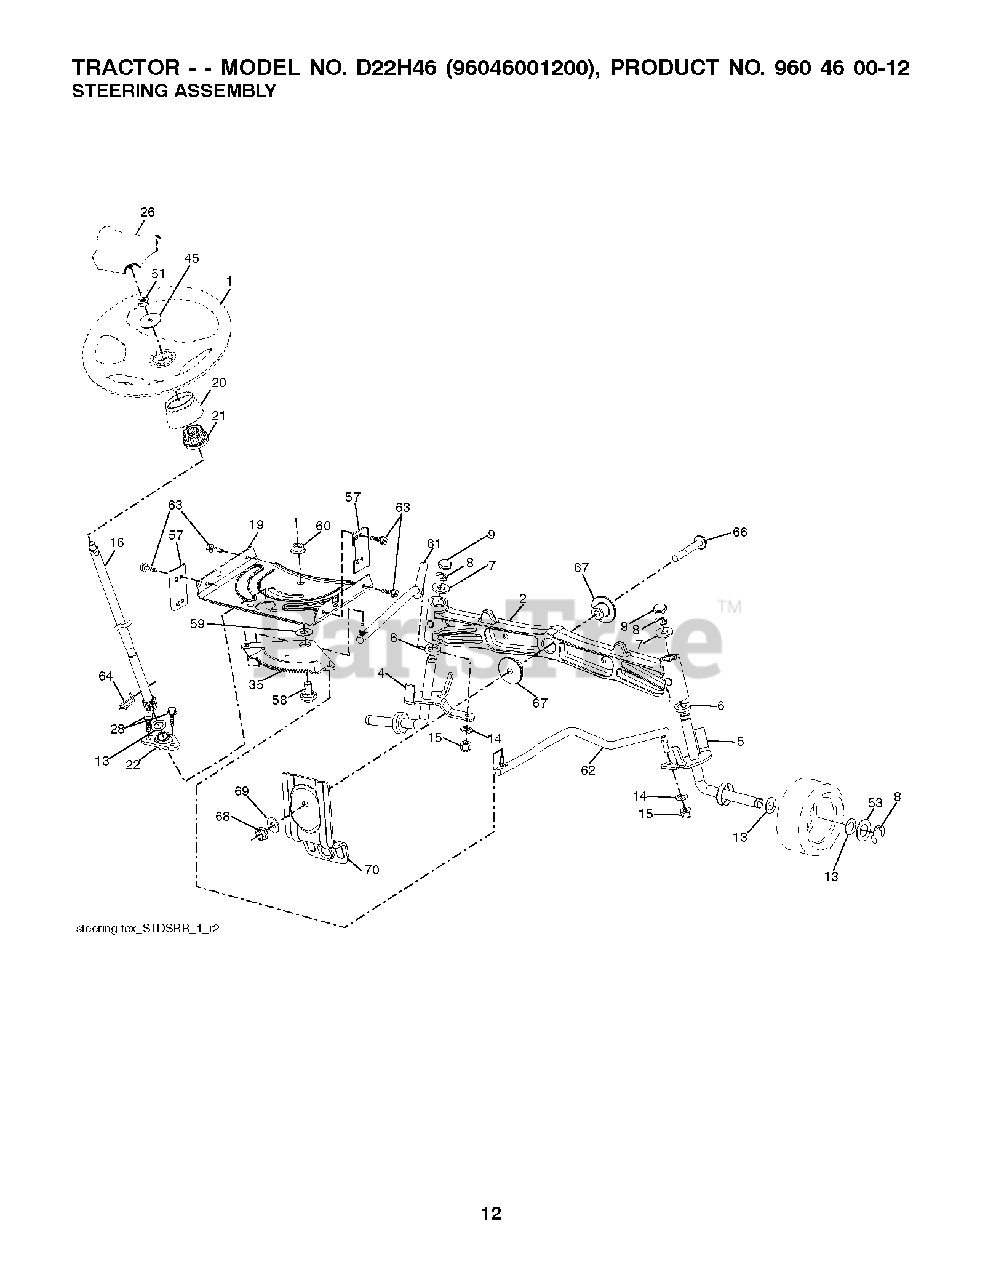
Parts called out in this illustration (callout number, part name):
1	WHEEL.STEERING.STDSRR.BLK/OV
2	AXLE.CAST.IRON
4	SPINDLE.WELDED.LH.15"TEX
5	SPINDLE.WELDED.RH.15"T
8	RING CLIP
9	CAP.SPINDLE.BLACK
14	WASHER, LOCK 3/8
15	NUT CROWNLOCK 3/8-24
16	SHAFT, STEERING
19	PLATE.STEER.DDL.NLT/NG
20	BOOT.STEERING.
21	ADAPTER, WHEEL STNG..
22	STEERING.SUPT.LOWER.
26	INSERT, WHEEL STEERING
28	SCREW, 3/8-16X3/4
35	GEAR.SECTOR.PLATE.DDL.
45	WASHER.11/32
51	NUT.HEX.1/2-20
53	WASHER.HARDENED
57	BRACKET.UPSTOP.TEX
58	BOLT.SHOULDER.SECTOR.P
59	WASHER.THURST.SECTOR.S
60	NUT FLANGE LOCK 5/8-11
61	DRAGLINK.LH.BALLSTUD.D
62	DRAGLINK.RH.BALLSTUD.D
63	SCREW
64	RETAINER.CLIP.SPRING.S
66	BOLT HEX FGHD 7/16-14 X 3 SERR
67	BUSHING.PM.FRONT AXLE
68	NUT.LOCK.FLANGE.7/16
69	WASHER.1.5X.505X.118
70	BRKT.DECK.SUSPENSION.F
